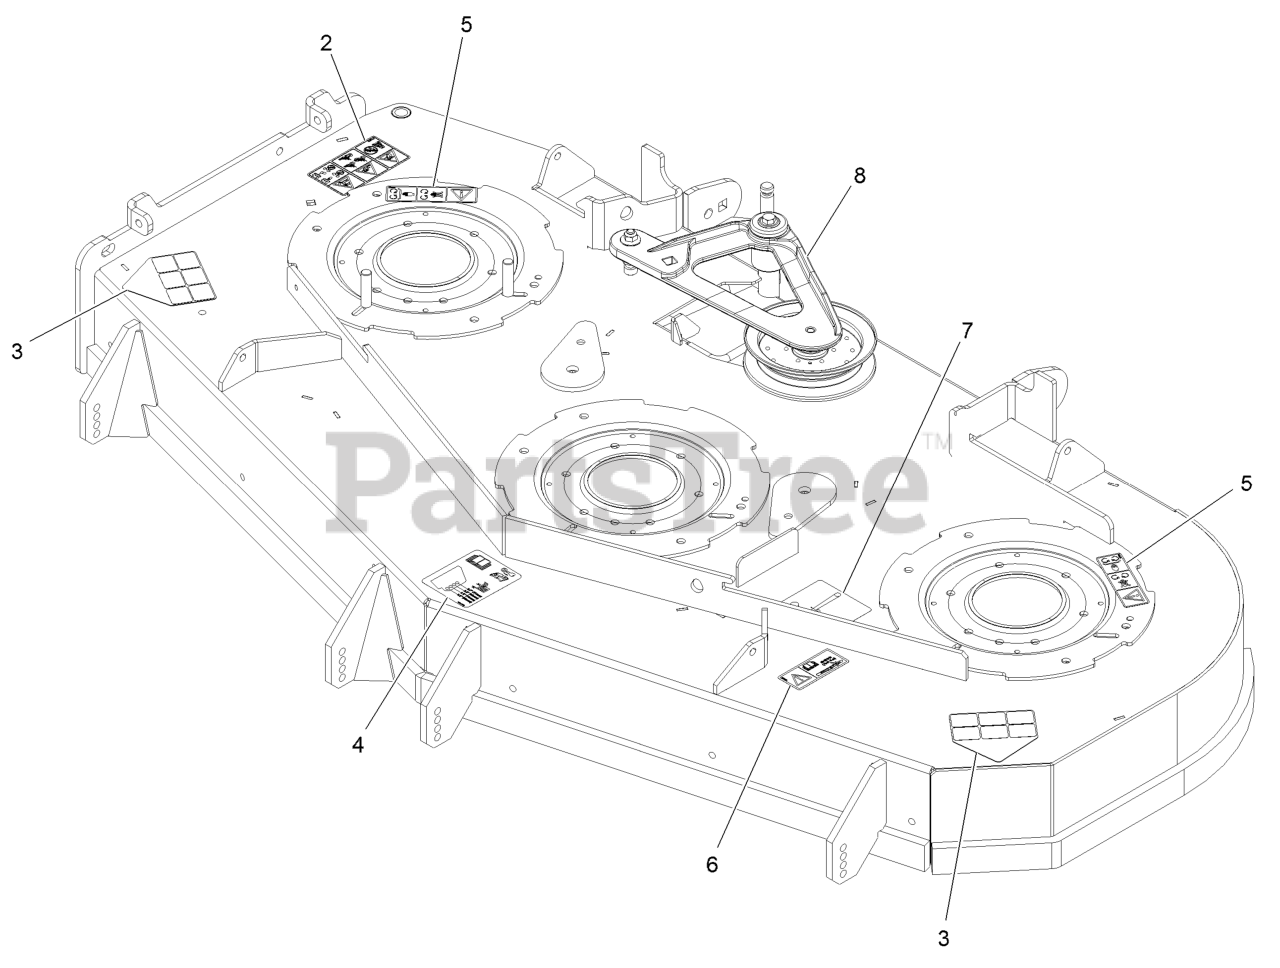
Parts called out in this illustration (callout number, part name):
2	DECAL-DANGER
3	DECAL-DANGER
4	DECAL-ROLLER, ANTI-SCALP
5	DECAL-COVER, MISSING
6	DECAL-BOLT TORQUE
7	DECAL-BELT ROUTING
8	DECK IDLER ASM
